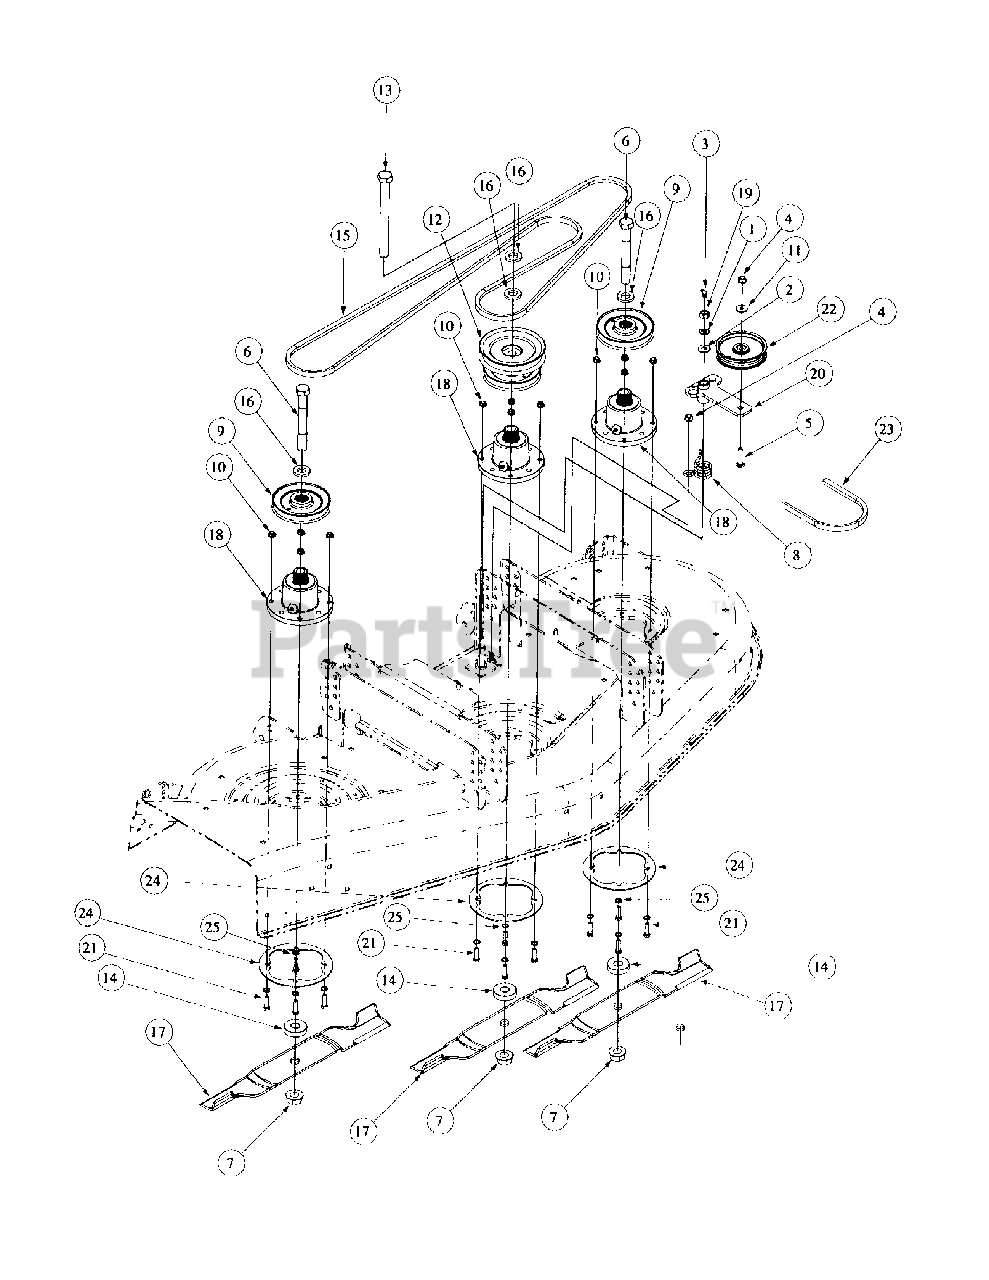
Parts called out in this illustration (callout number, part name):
1	Lock, Washer, 1/2, Zinc
2	Flat, Washer, 1/2, Zinc
3	Grease Fitting, 1/4-28 x 3/16
4	Hex, Nut, Flange Lock, 3/8-16
5	Hex Carriage, Screw, 3/8-16 x 1.75
6	Hex, Cap Screw, 3/4-16, 6.00
7	Hex, Flange, Nut, 3/4-16
8	Idler Torsion Spring
9	Pulley-V, 4.65 P.D.
10	Hex flange, Lock, Nut, 5/16-18
11	Flat Washer, 406 ID x 1.0 OD, .105
12	Double Pulley
13	Hex, Cap, Screw, 3/4-16, 8.00
14	Spacer, .76 ID x 2.0 OD x 477
15	V-Belt, "A" Sec x 122" Long
16	Spacer, 812 ID x .268 Long
17	High Lift Blade, 20.5
18	60 Deck, Aluminum Spindle Assembly
19	Hex Nut, 1/2-20
20	Idler Arm Assembly, Bearing, 60 Deck, Black
21	Hex Cap Screw, 5/16-18, 1-1/4
22	Flat Pulley with Flanges
23	V-Belt, B Section x 68.04
24	Reinforcement, Deck, Plate
25	Flat Washer, 5/16
